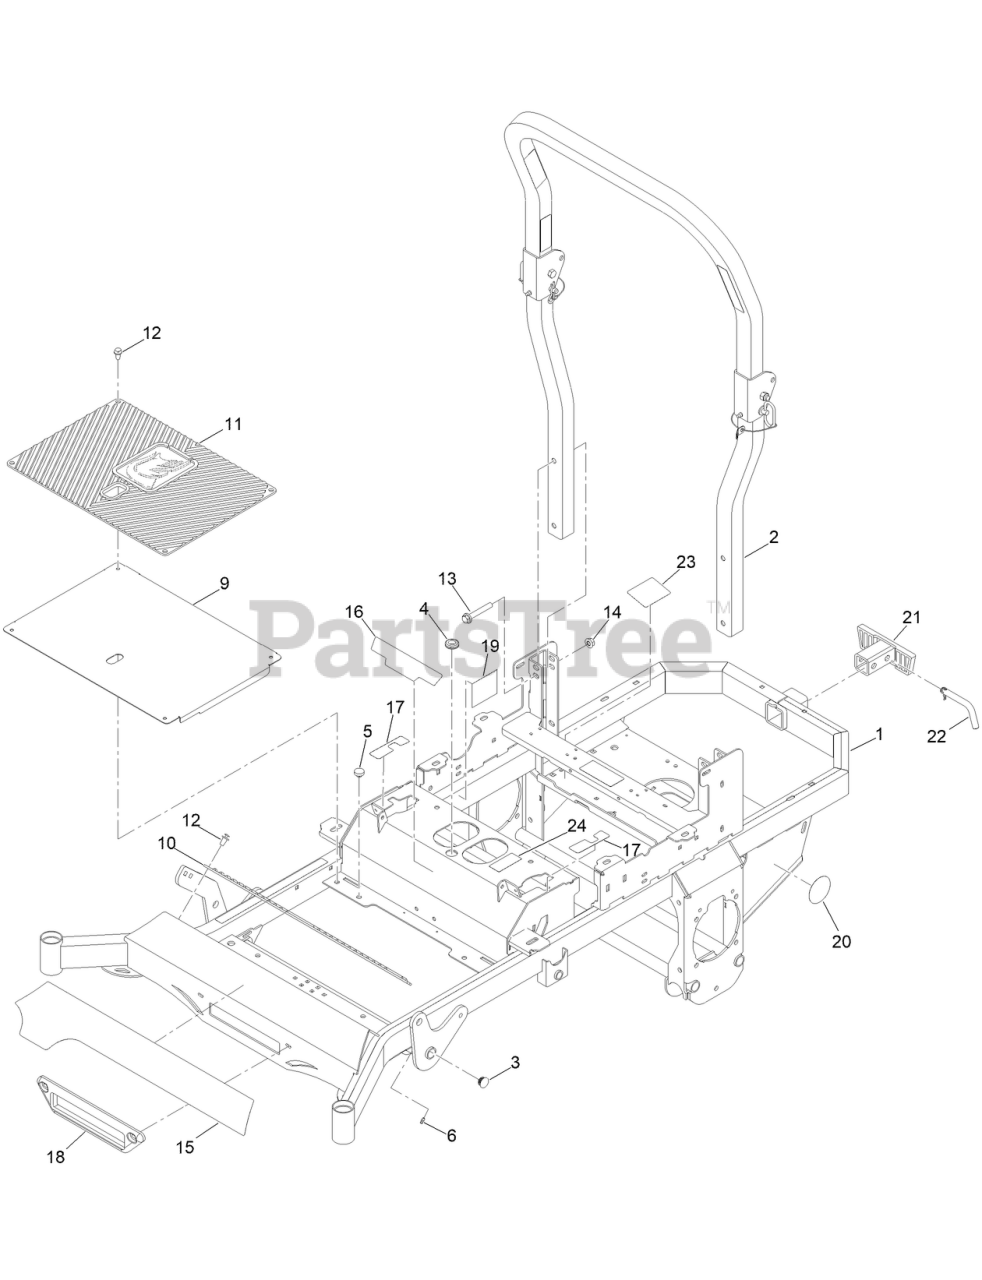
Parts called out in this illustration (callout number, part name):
1	ASM FRAME W/ DECALS
2	MWR FOLD DOWN ROPS
3	1-1/4 IN ROUND TUBE PLUG
4	GROMMET-RUBBER
5	PUSH-IN RUBBER BUMPER MWR FLOOR
6	1/4 DRIVE TYPE STRAIGHT GREASE FITTNG ZC
9	MWR FLOORBOARD BLACK
10	MWR RUBBER FOOT REST MAT
11	MWR LOGO FLOOR MAT
12	8MM PUSH TYPE RETAINER NYLON BLACK
14	1/2-13 HEX STOVER LOCKNUT GR C ZINC
15	2022 KGZ FLOORBOARD DECAL
16	2022 KGZ-XD W/GT TRAC DECAL
17	DECAL-MOTION CONTROL
18	MWR FT NYLON BUMPER
19	DECAL-E P A
20	DECAL-PARKER PUMP
21	MWR RR RECEIVER NYLON BUMPER
22	HITCH PIN SHORT FOR INTMDR RR HITCH
23	DECAL-PUMP BELT ROUTING-PARKER
24	DECAL-WEIGHT, SEAT
